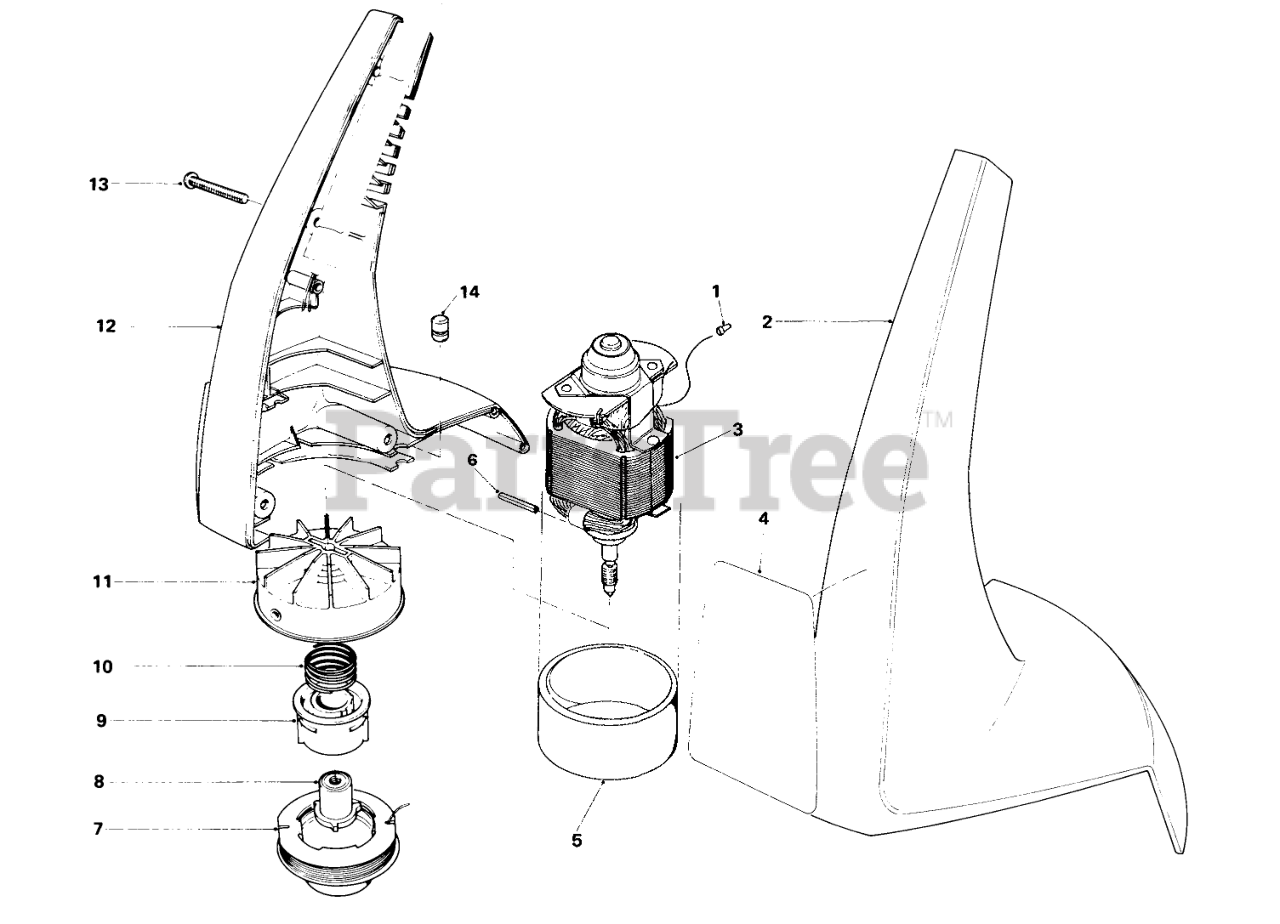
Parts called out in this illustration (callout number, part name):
6	COIL PIN
7	Prewound Spool
8	DRIVER DETENT
9	CORE - SPOOL
10	SPRING-COMPRESSION
11	FAN HUB ASM
